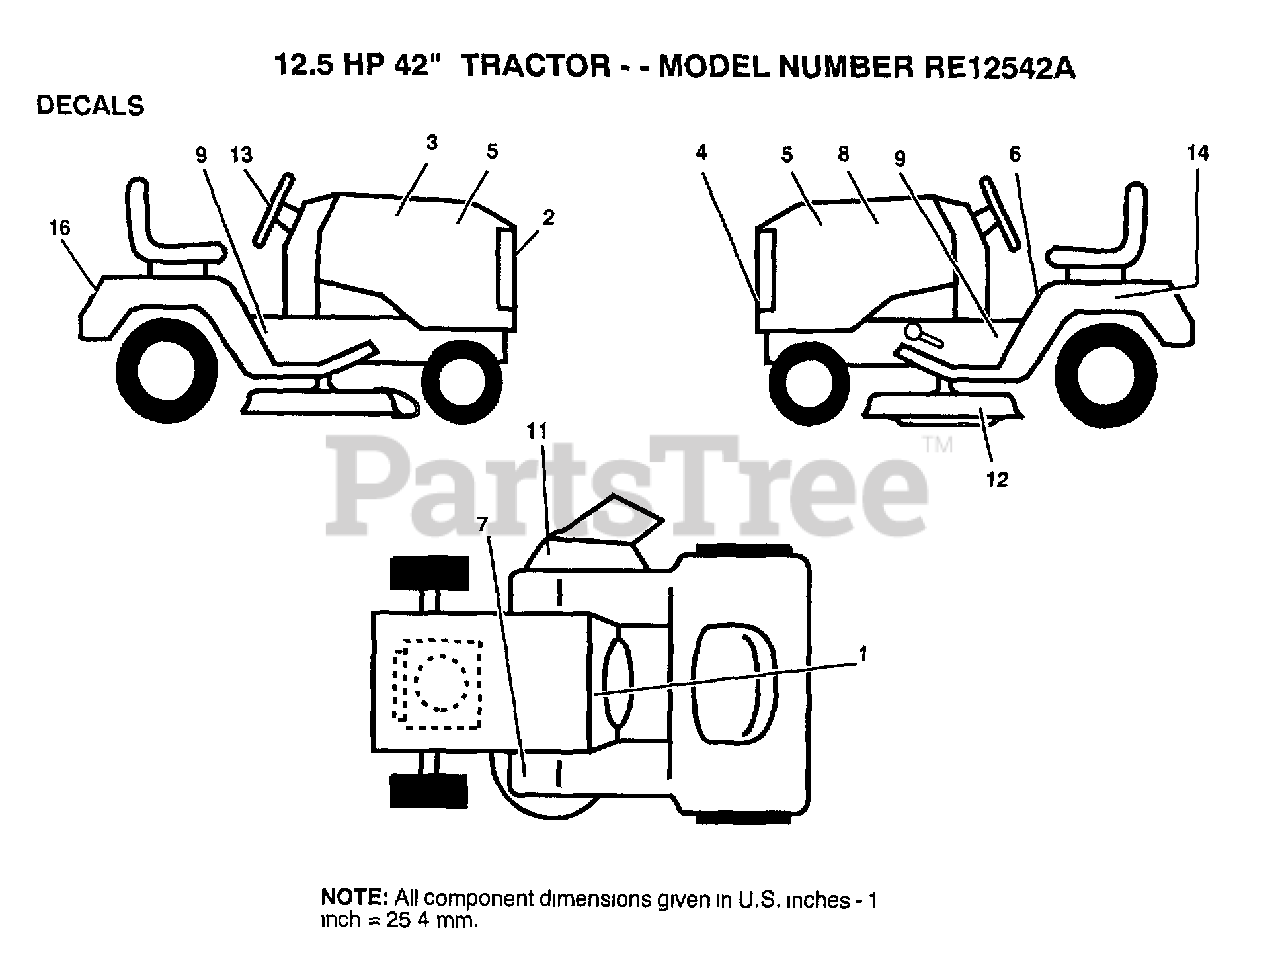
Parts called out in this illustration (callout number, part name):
2	GRILL DECAL
5	"DECAL,HOOD"
6	DECAL CAUTION
7	DECAL T
9	CHASSIS DECAL
11	DECAL WARNING
12	DECAL YT
13	"DECAL,STR WHL"
14	DECAL
16	FENDER DECAL
